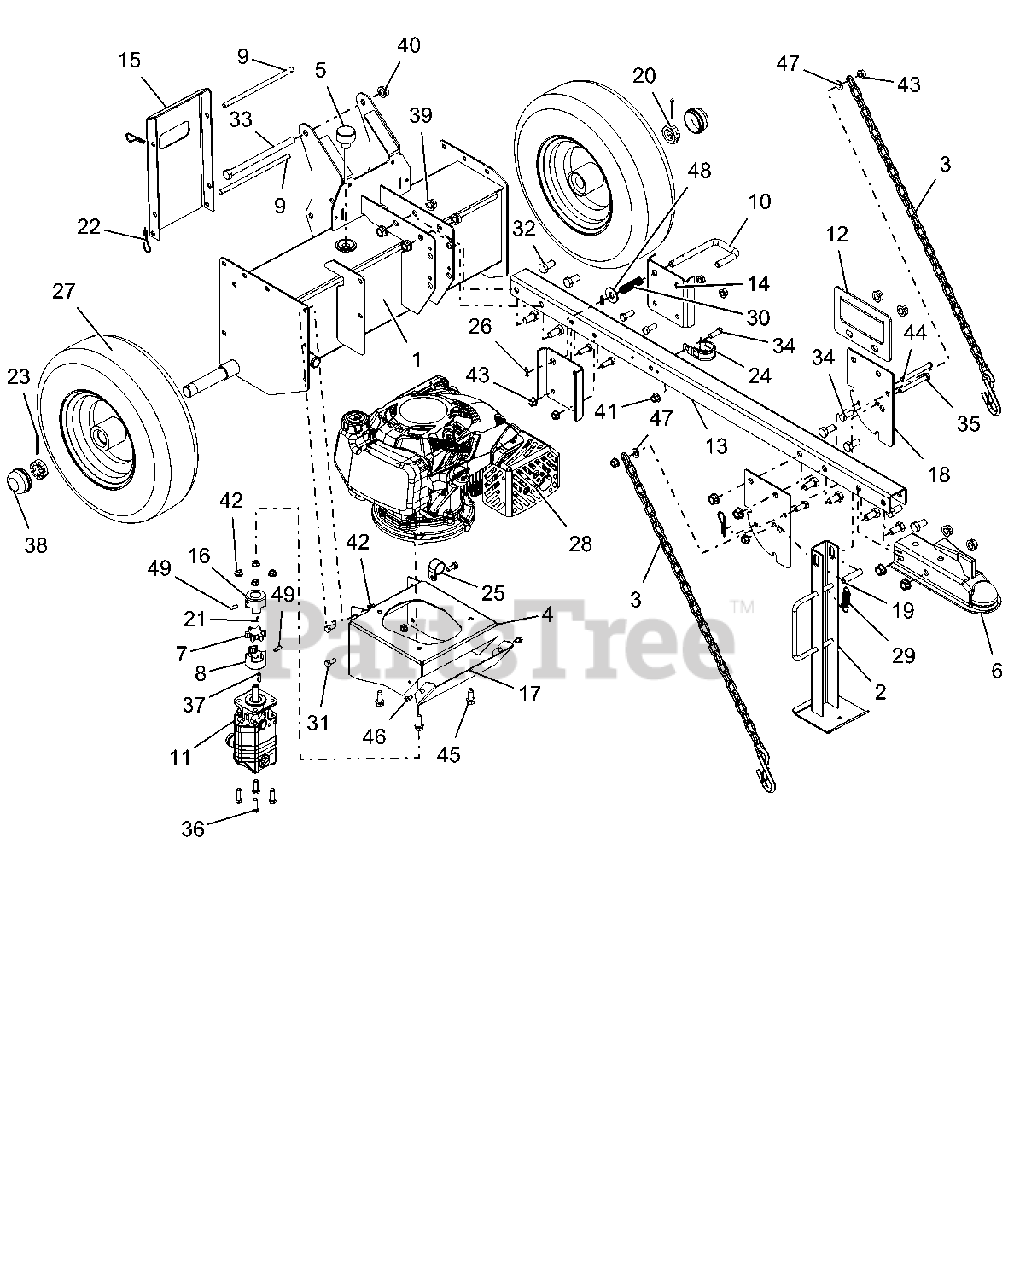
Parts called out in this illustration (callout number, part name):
1	WMT,SMALL CHASSIS
2	WLDMT, JACK STAND
3	CHAIN, SAFETY 3/16"-30LINK
4	WLDMT,ENGINE/PUMP
5	BREATHER, DIPSTICK
6	HITCH, BALL-2"
7	SPIDER - URETHANE
8	COUPLER - DRIVE 1/2"
9	PIN, .373 X 7.30 X 2X.109 THRU
10	LOCK, BEAM
11	PUMP,SPLITTER-11 GPM
12	HANDLE, SPLITTER DRAW BAR
13	BAR, DRAW
14	GUIDE, LOCK DOWN
15	SUPPORT, REAR LEG
16	COUPLER - DRIVE, 7/8"
17	COVER, COUPLING
18	MOUNT, SPRING LOADED JACK
19	SPCR, WHEEL .385X.500X2.00
20	NUT-SL 1.0-14
21	KEY-WDRF .125X.50X.20 (HRDEND)
22	HAIRPIN, #7 CLIP .094X2.31 YWZ
23	@PIN-CTR .15X1.50 YWZC
24	CLAMP, CUSHIONED STEEL 1.25
25	CLAMP, COUSHIONED STEEL REV
26	CLIP, SPRING
27	WHEEL, SPLITTER
28	ENGINE, SUBARU EA175V
29	SPRG, TENSION .063X.625X2.50
30	SPRG, COMP .058X.65X2.13 WLD15
31	@BLT-HEX .31-18X.75 GR5 YWZC
32	@BLT-HEX .50-13X1.00 GR5 YWZC
33	@BLT-HEX .50-13X7.50 GR5 YWZC
34	@BLT-HEX .38-16X1.00 GR5 YWZC
35	@BLT-HEX .38-16X3.00 GR5 YWZC
36	@BLT-HEX .31-18X1.00 GR5 YWZC
37	KEY-SQ .188X.75X.188
38	CAP, DUST
39	NUT-LK-CTR-FLG .50-13 YWZC
40	NUT-LK-CTR-FLG .50-13 YWZC
41	@NUT-LK-NYL-FLG .38-16 YWZC
42	@NUT-LK-TOP-FLG .31-18 YWZC
43	@NUT-LK-TOP-FLG .38-16 YWZC
44	PIN-CLEV .371X3.25 YWZC
45	@SCR-TAP .38-16X1.00 HWH TR YZ
46	SCR-TAP .25-20X.50 HWH TR YWZ
47	@WSHR-FL-STL.406X.812X.065 YWZ
48	@WSHR-FL-STL.563X1.38X.109YWZC
49	SCR,SET .25-20X.75 PCPT SH
